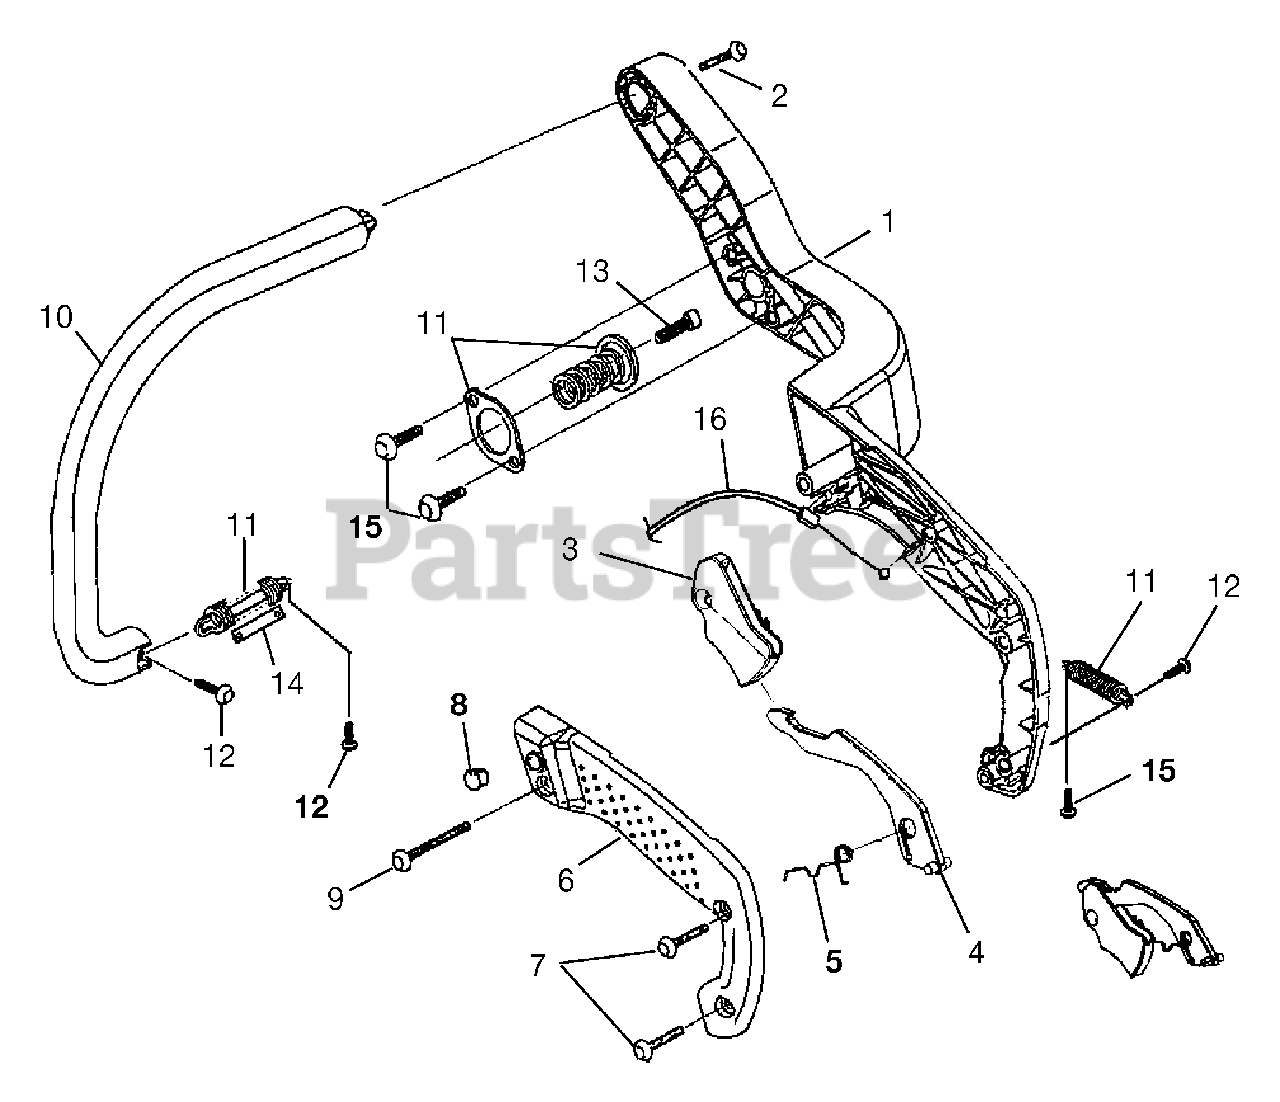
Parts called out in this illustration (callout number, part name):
1	Rear Handle Kit
2	Screw-Pan Hd. (12-14 x 1 1/2")
3	Trigger, Throttle
4	Throttle Lock Out
5	Torsion Spring
6	Handle Cover Kit
7	Screw, Thread Form (10-14 x 3/4")
8	Plug-Plastic
9	Screw, Thread Form (10-14 x 1 3/8")
10	Front Handle Kit
11	Isolator Kit
12	Screw, Truss Hd. (10-14 x 5/8)
13	Screw, Truss Hd. (10-24 x 5/8")
14	Limiter, Isolator
15	Screw, Thread Form (10-14 x 1/2")
16	Throttle Cable
